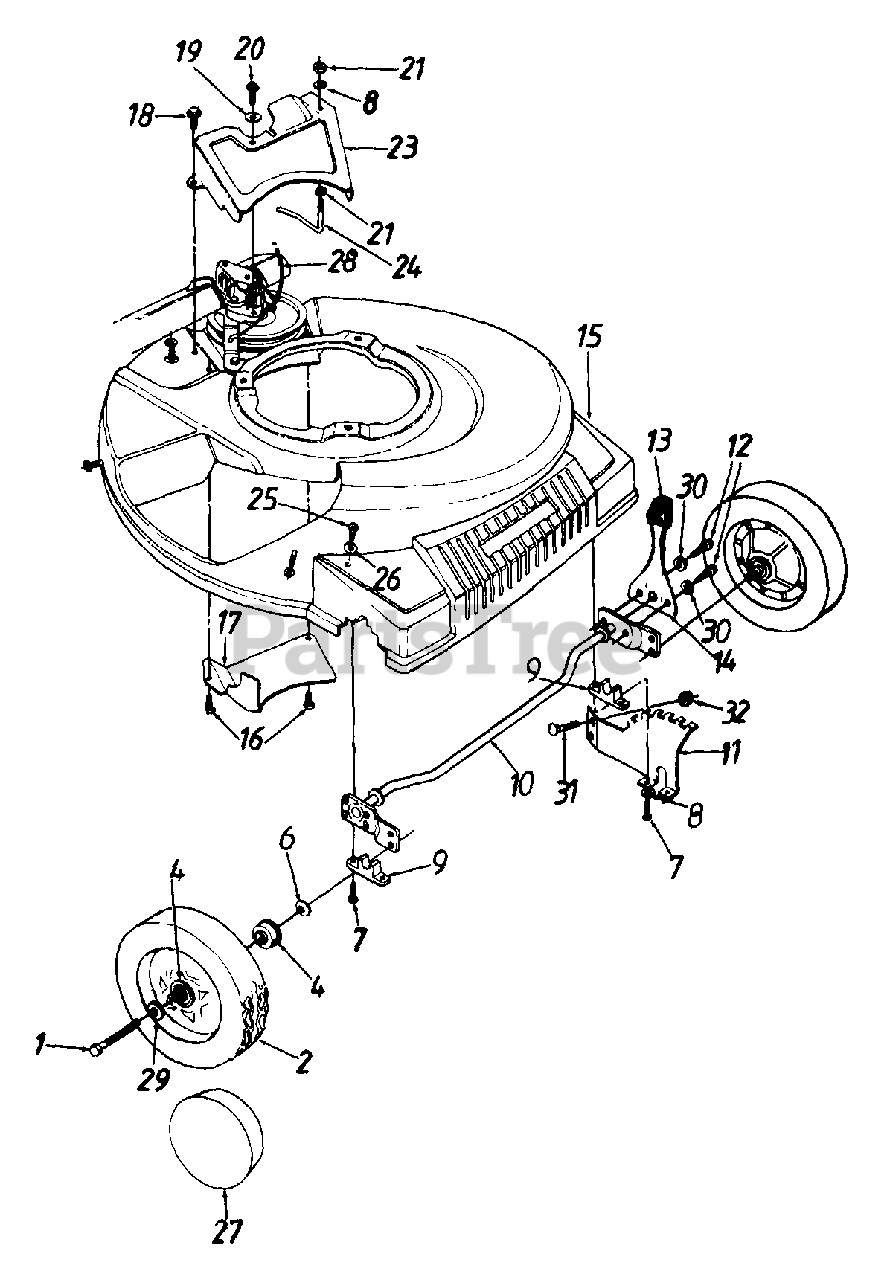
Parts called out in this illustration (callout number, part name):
1	Front Axle Bolt
2	Wheel Ass'y. Comp
4	Flange Ball Brg. .501" I.D.
6	Bell-Wash. .380" I.D. x .88
7	Hex Wash. Hd. Scr 1/4-20 x 1" Lg
8	L-Wash. 1/4" I.D.
9	Block Bushing
10	Axle Ass'y
11	Height Adj. Bracket
12	Hex Wash. Hd. TT-Tap Scr. 1/4-20 x .38" Lg
13	Knob
14	Spring Lever
15	Plastic Front End
16	Hex B-Tap Scr 1/4" x .38"
19	Bell-Wash .265" I.D. x .75"
20	Hex Wash. Hd B-Tap Scr. 1" x .62" (Spec.)
21	Hex Nut 1/4-20 Thd.
25	Torx Truss Hd. Scr. 5/16 x 75"
26	Bell-Wash. .345" I.D. x 88" O.D.
27	Hub Cap
28	S.P. Cable 50" Lg.
29	Wave Wash. .51" I.D. x .75" O.D.
30	External L-Wash 1/4" I.D.
31	Carr. Bolt 1/4-20 x .5" Lg.
32	Hex L-Nut 1/4-20 Thd.
